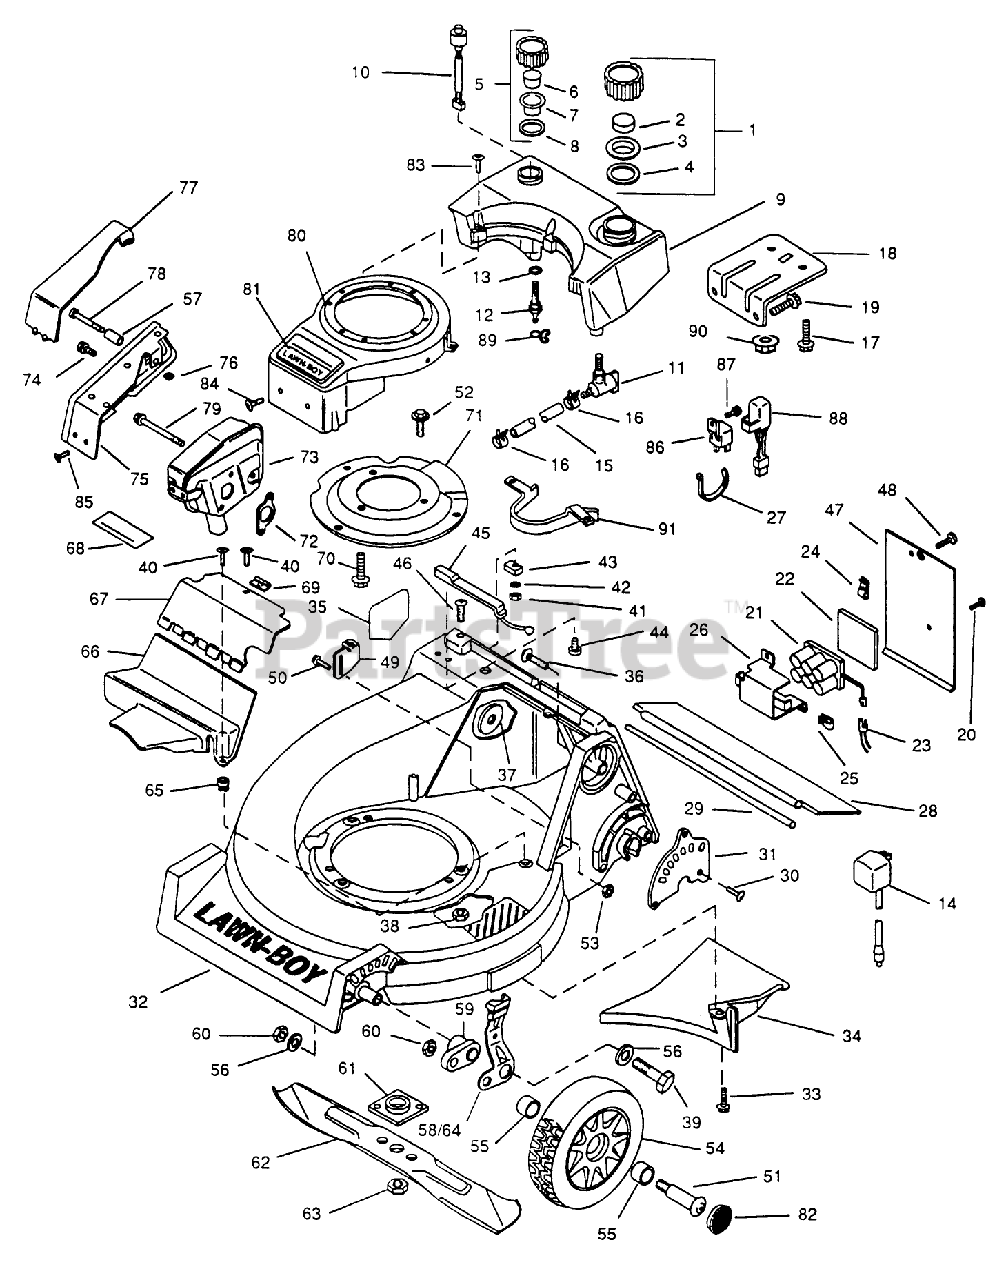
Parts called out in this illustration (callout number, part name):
1	CAP AY - FUEL M
2	BAFFLE - FOAM SM
3	COVER-FUEL CAP F
4	GASKET-FUELCAP SM
5	CAP AY. OIL M
10	SWITCH AY-OIL S
11	DISC/LB SER.BUL.#6
13	O-RING SM
15	GAS LINE SM
16	HOSE CLAMP SM
17	DISC/LB SER.BUL.#6
18	DISC.LB SER BUL.#6
19	SCREW-HEX W.H. SM
22	PAD-BATTERY
23	WIRE HARNESS
24	SPEED NUT LARSON
25	SPEED NUT ARDEN
27	TIE-CABLE
30	SCREW-BHTF
32	HOUSING ASM.
34	CHUTE BAFFLE NYL
38	NUT-LOCK F
47	DOOR-ACCESS ELECT.
48	SCREW-CROSS RECESS
49	ANCHOR-CABLE
51	SHOULDER BOLT
52	SCREW-HH
53	LOCKNUT E
55	Bushing
56	WASHER-PLAIN
57	SPACER S
58	KNOB & SPRING CMS
59	ARM HGT ADJ *BLACK
60	NUT-JAM, LOCKING
61	PLATE AND COLLAR ASM
63	NUT-BLADE
64	KNOB & SPRING CMS
65	NUT-CLIP
69	NUT-SPEED
71	PLATE SM
72	GASKET - EXH SM
74	SCREW S
75	MUFFLER GUARD AY
76	NUT-PUSH
77	COVER MUFFLER CP
78	SCREW SM
79	SCREW-SEMS
81	APPLIQUE SM
82	CAP-HUB
83	DISC.LB SER.BUL.#6
85	SCREW SM
